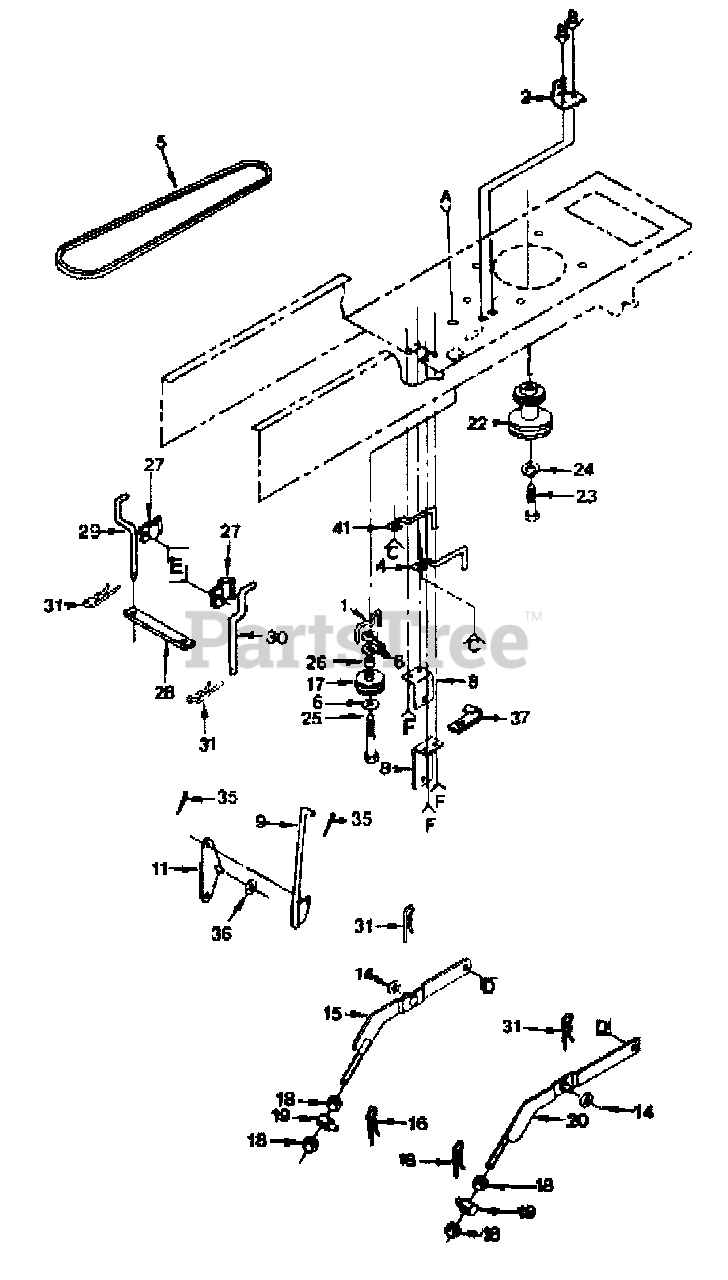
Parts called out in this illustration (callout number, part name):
1	Keeper, Belt
2	Bracket, Switch
4	Keeper, Belt, Engine
5	V-Belt, Drive
6	Washer 13/32 x 13/16 x 12 Ga.
8	Bracket, Bellcrank
9	Rod Assembly, Clutch Primary
11	Bellcrank Assembly
14	Washer 17/32 x 15/16 x 16 Ga.
15	Arm Assembly, Suspension, L.H.
16	Retainer, Spring
17	Idler, Flat
18	Nut, Hex 1/2-13
19	Trunnion, Lift Lower
20	Arm Assembly, Suspension R.H.
22	Pulley, Engine
23	Bolt, Hex 7/16 - 20 x 1 - 1/4 G8
24	Washer, Lock
25	Bolt, Hex 3/8 - 16 x 2 - 3/4
28	Strap, Locater
29	Keeper, Belt, L.H.
30	Keeper, Belt, R.H.
31	Spring, Retainer
35	Pin, Cotter 1/8 x 3/4
36	Washer, 13/32 x 7/8 x 10 Ga.
37	Clip, Insulated
41	Keeper, Belt, Engine
